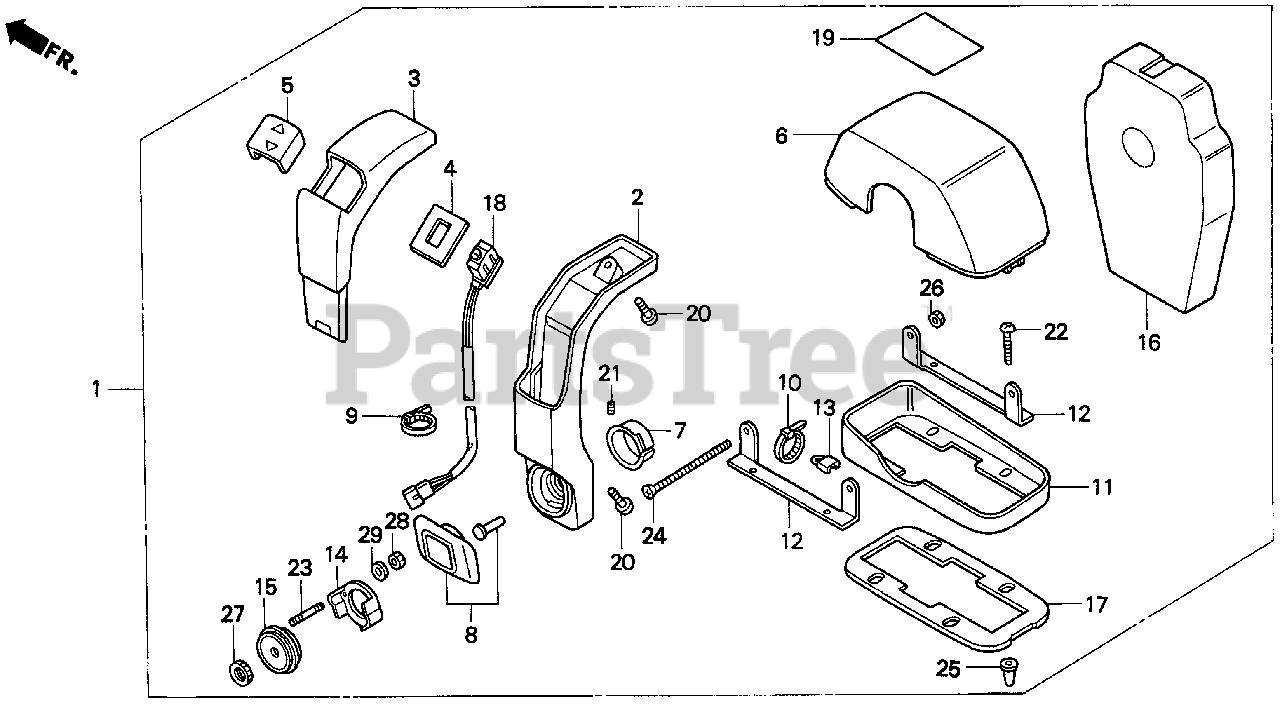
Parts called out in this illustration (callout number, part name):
1	BOX ASSY., REMOTE CONTROL (TOP MOUNT SINGLE) (NA USE ALT:24800-ZW7-V01)
2	HANDLE, REMOTE CONTROL
3	GRIP, REMOTE CONTROL HANDLE
4	PLATE, SWITCH SETTING
5	COVER, GRIP
6	HOUSING ASSY., REMOTE CONTROL BOX (A)
8	BUTTON ASSY.
9	BAND A, CABLE
10	BAND B, CABLE
11	HOUSING ASSY., REMOTE CONTROL BOX (B)
12	BRACKET, REMOTE CONTROL HOUSING
14	BRACKET, SWITCH MOUNTING
15	PLATE ASSY., SWITCH MOUNTING
16	HOUSING ASSY. (INNER) (TOP MOUNT)
18	SWITCH ASSY., POWER TRIM-TILT (A)
19	MARK, REMOTE CONTROL (SINGLE)
20	SCREW (10-32X1")
21	SCREW SET (1/4-20X16")
22	SCREW (10-32X1-1/2")
23	STUD (10-32X2")
24	SCREW (10-32X2-1/4")
25	NUT, WELDING (10-32)
26	NUT (10-32)
27	NUT, LOCK (15/32-32)
28	NUT (10-32)
